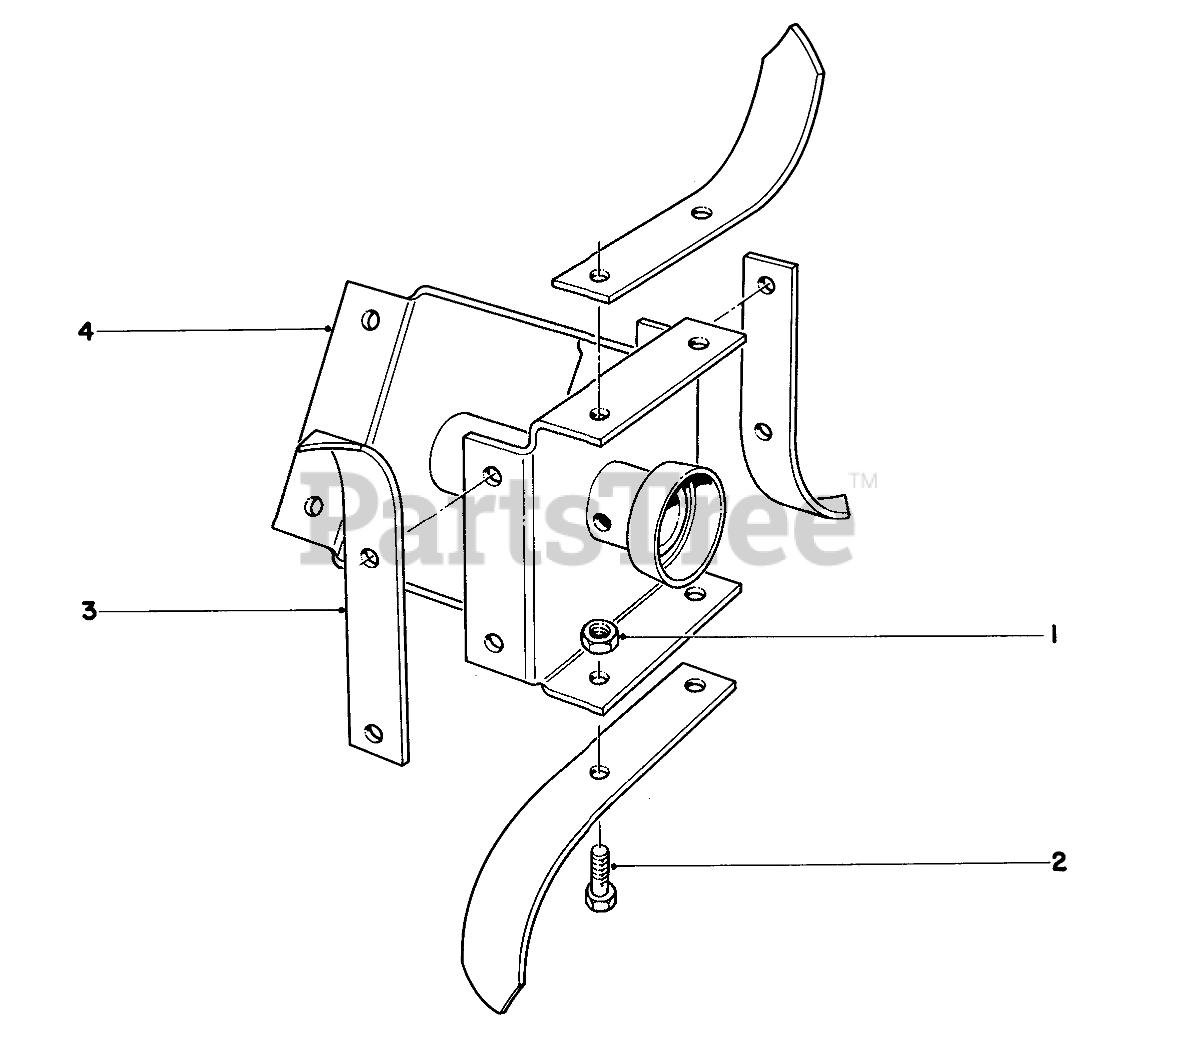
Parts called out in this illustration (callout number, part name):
1	NUT-LOCK, CONE
2	Capscrew
3	Pick Tine
4	Axle Welded R.H.
